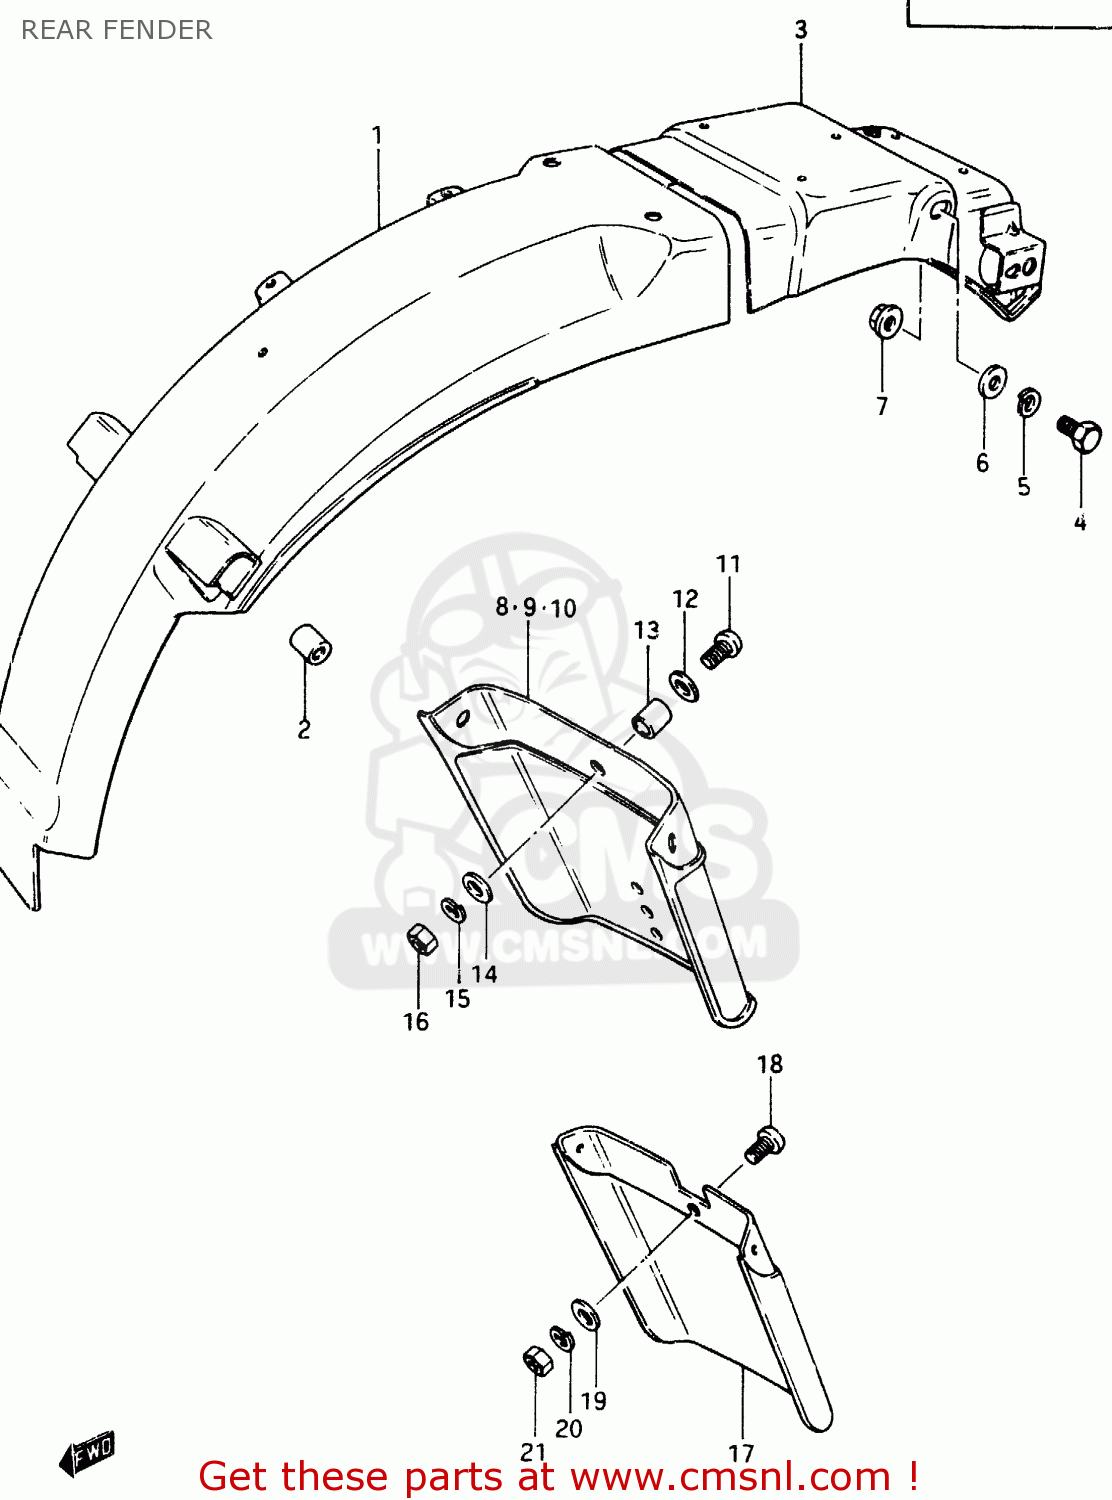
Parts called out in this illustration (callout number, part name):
1	BODY,REAR FENDER,FRONT
2	CUSHION
3	REINFORCEMENT,RR FENDER
4	BOLT,8X1.25X2
5	WASHER,LOCK,8.
6	WASHER 8MM
7	NUT, WHEEL SET
8	EXTENSION, REAR
9	EXTENSION,RR F
10	EXTENSION, REAR
11	SCREW
12	WASHER
13	SPACER(6.2X8.3X5.7)
14	WASHER
15	WASHER,LOCK
16	NUT 6MM
17	MUD GUARD
18	SCREW
19	WASHER
20	WASHER,LOCK
21	NUT
